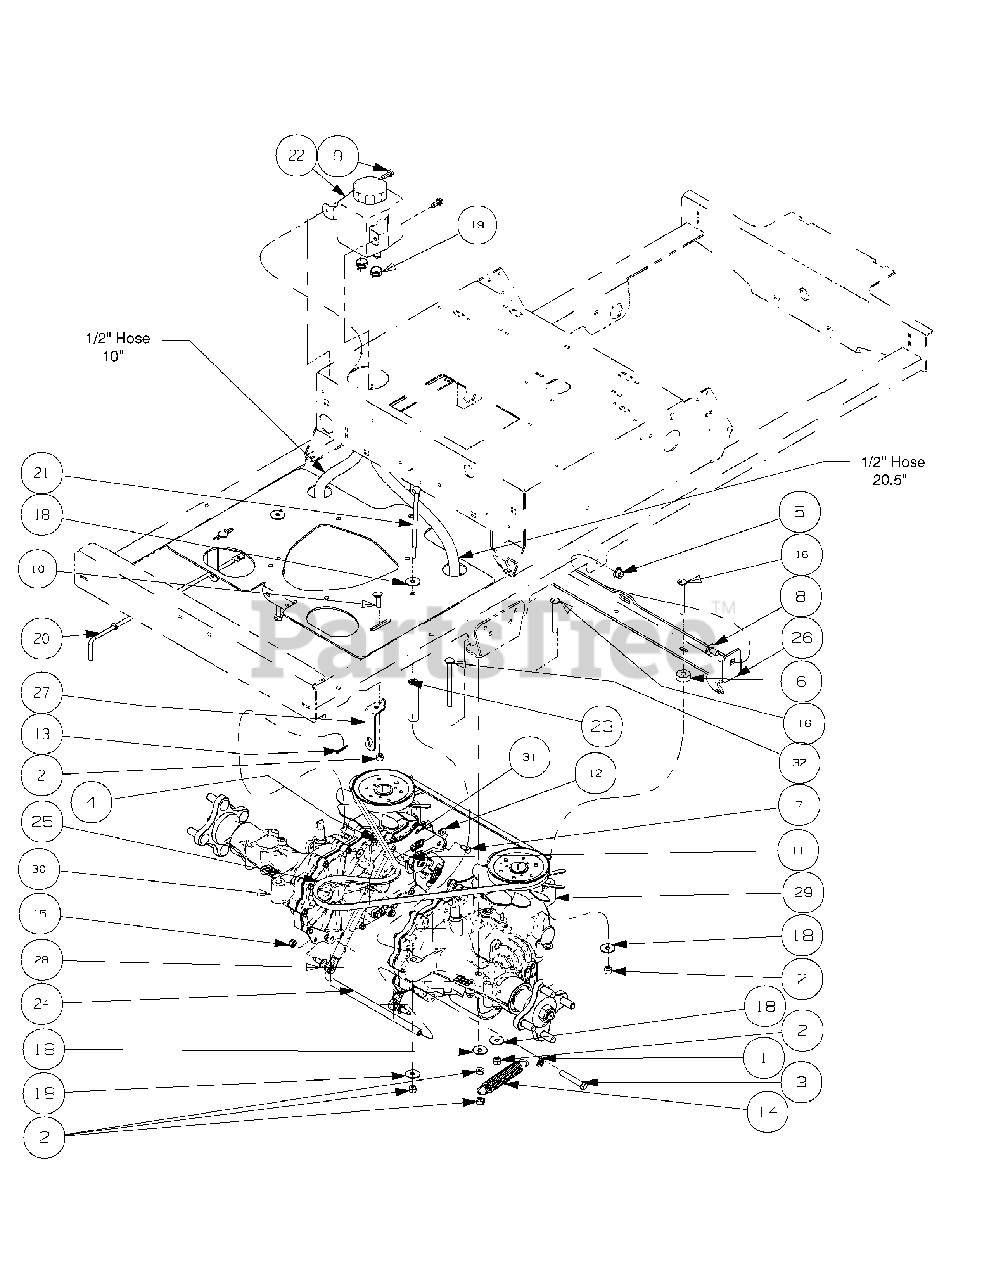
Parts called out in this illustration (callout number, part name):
1	Lock Washer, 3/8 Zinc
2	Nylock Nut, 5/16-18
3	Hex Cap Screw, 3/8-16 x 2.00
4	Nut, 1/4-28, SS, Nylon Insert
5	Nut, Flange Lock, 3/8-16
6	Spacer .406 ID x 1.0 OD
7	Hex Cap Screw 1/4-20 x .620
8	Carriage Bolt, 3/8-16
9	Self Tapping Screw, 1/4-20 x .75
10	Carriage Bolt, 5/16-18 x 1.00
11	Shoulder Screw, 1/4-28
12	Nut, 1/4-20, Hex Flange Lock Nut
13	Cotter Pin, .072 x 1.12 Lg
14	Extension Spring, .865 OD x 4.68 Long
15	Nut, Hex, Center Lock, M8
16	Carriage Bolt, 5/16-18 x 2.75
17	Fuel Hose, .50 ID x .75 OD x 30.5"
18	Washer, 5/16 x 1.06
19	Hose Clamp
21	Hex Cap Screw, 5/16-18 x 6.00
22	Hydraulic Tank
23	Spacer, .375 ID x .75 OD x 3.30
24	Transmission Support Tube
25	V-Belt, 58.4
26	Transmission Front Mounting Bracket
27	Neutral Bracket
28	Cylinder Return to Neutral
29	2800 Charged Transmission, Right Hand
30	2800 Charged Transmission, Left Hand
31	Return to Neutral Bracket
32	Carriage Bolt, 5/16-18 x 4.00
